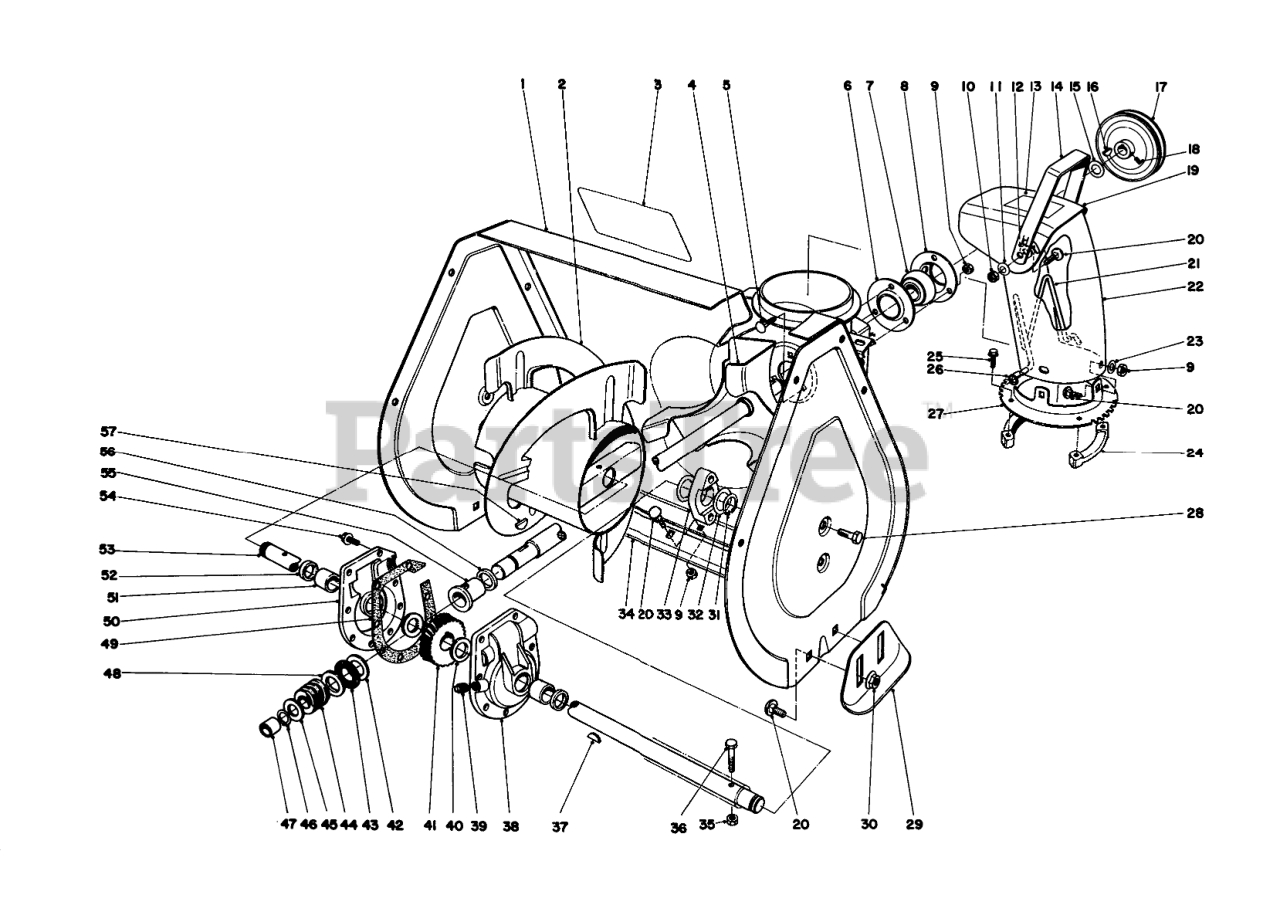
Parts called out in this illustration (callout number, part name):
1	Auger Housing
2	Auger R.H.
3	Decal-Warning
4	Shaft & Impeiler
5	BOLT-CARR
6	FLANGE-CUP, BEARING
7	Ball Bearing
8	FLANGE-CUP, BEARING
9	NUT-LOCK, NI
10	NUT-LOCK, CONE
11	WASHER-BELLEVILLE
12	WASHER-RUBBER
13	Decal-Danger
14	Handle Deflector
15	WASHER
16	KEY-WOODRUFF
17	PULLEY
18	SCREW-SET, SQH
19	Deflector (Incl. Ref. #13)
20	BOLT-CARR
21	CHUTE WIRE
22	DISCHARGE CHUTE
23	WASHER-PLAIN
24	RING-CHUTE, RETAINER
25	SCREW-SPECIAL
26	NUT-PUSH
27	Chute Ring
28	SCREW-HWHTF
29	Skid
30	NUT-HF
31	RING-RETAINING
32	WASHER
33	BEARING-AUGER
34	Blade-Scraper
35	NUT-LOCK, CONE
36	SCREW-HH
37	KEY-WOODRUFF
38	Gear Case L.H. (Incl. Ref. #51 & 52)
39	PLUG-PIPE, SQH
40	WASHER-THRUST
41	Gear
42	WASHER-THRUST
43	BEARING-THRUST
45	WASHER-THRUST
46	Ring-Snap
47	BUSHING
48	WASHER-THRUST
49	GASKET-CASE, GEAR
50	Gear Case R.H. (Incl. Ref. #51 & 52)
51	BUSHING
52	SEAL-OIL
53	AUGER SHAFT
54	SCREW-TAPTITE
55	BUSHING-INPUT
56	RING-QUAD
57	KEY-WOODRUFF
